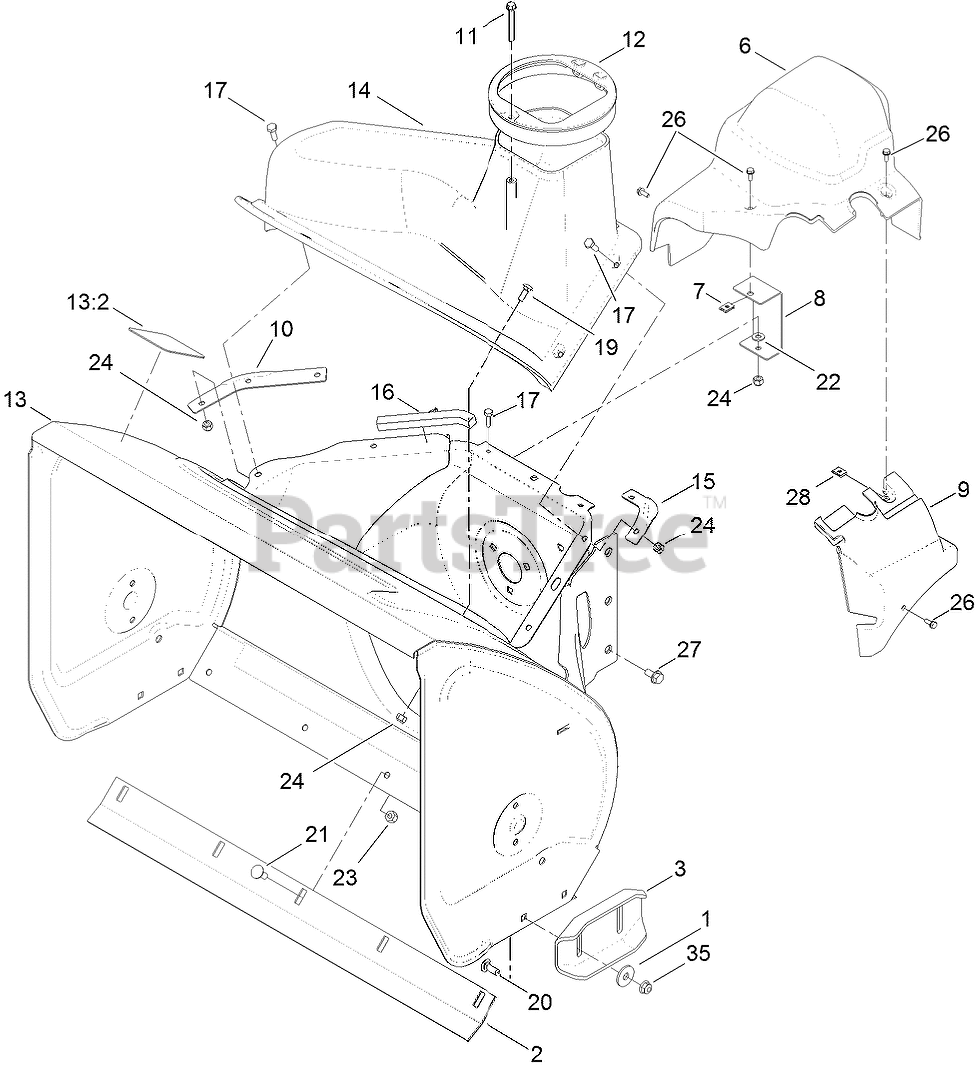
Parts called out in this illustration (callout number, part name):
1	WASHER
2	SCRAPER-FIXED
3	SKID-CAST
6	COVER-BELT
7	NUT-SPEED, U-TYPE
8	BRACKET-COVER, CLIP NUT
9	COVER-EXTENSION, BELT
10	SEAL-FLANGE, COVER
11	SCREW-PLASTITE
12	GUIDE-CHUTE
13	HOUSING-AUGER, 26 INCH
13:2	DECAL-DANGER, AUGER
16	SEAL-HOUSING
17	SCREW-HH
19	BOLT-CARR
20	SCREW-CARR
21	SCREW-CARR
22	WASHER-FLAT
23	NUT-LOCK, NI
24	NUT-LOCK, NI
26	SCREW-HWH
27	SCREW-HWHTF
28	NUT-SPEED
35	NUT-HF, NI
